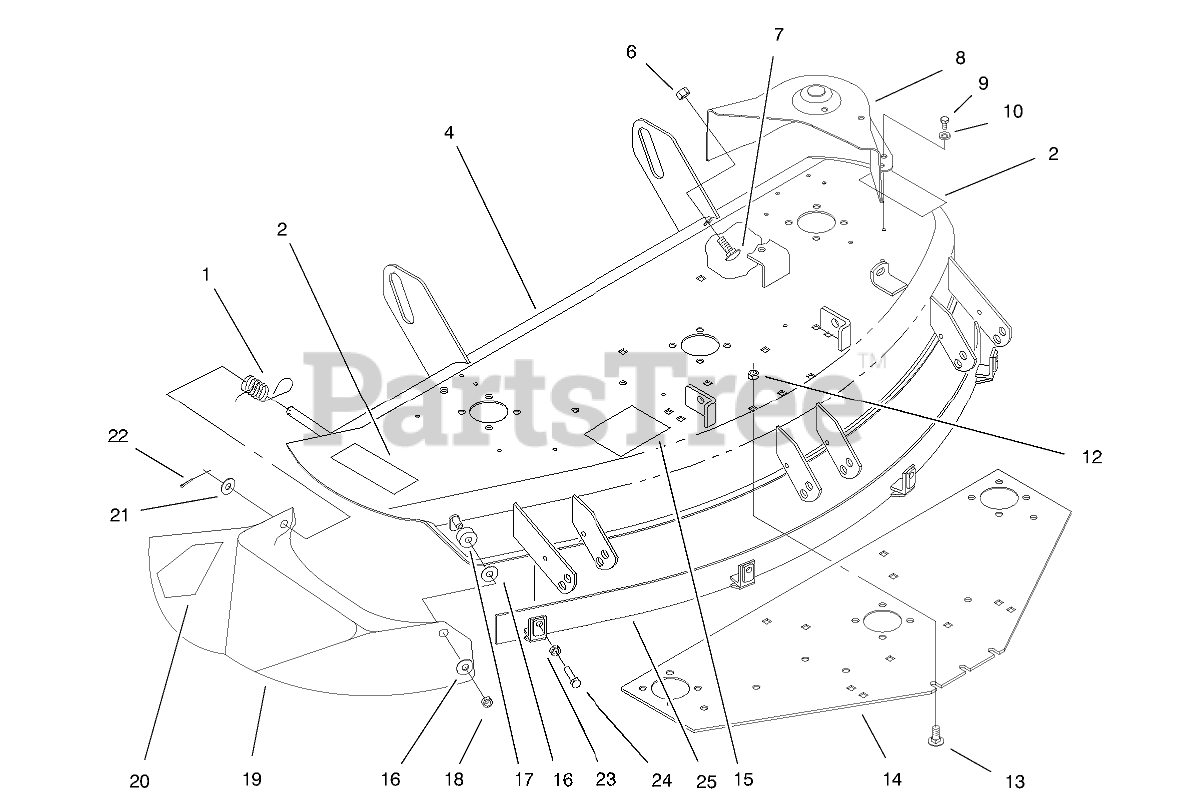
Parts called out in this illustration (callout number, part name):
1	SPRING-DEFLECTOR
2	DECAL-DANGER
4	DECK ASM
6	NUT-LOCK, NI
7	SCREW-CARR
8	COVER-BELT
9	SCREW-HWH
10	WASHER-FLAT
12	NUT-LOCK, NI
13	SCREW-CARR
14	Plate-Deck
15	DECAL - BELT INSTALLATION
16	WASHER
17	BUSHING-PIVOT
18	NUT-HJ
19	Chute Extension
20	DECAL-DANGER
21	WASHER-FLAT
22	PIN-COTTER
23	NUT-JAM
25	WA-FRONT SHIELDR
